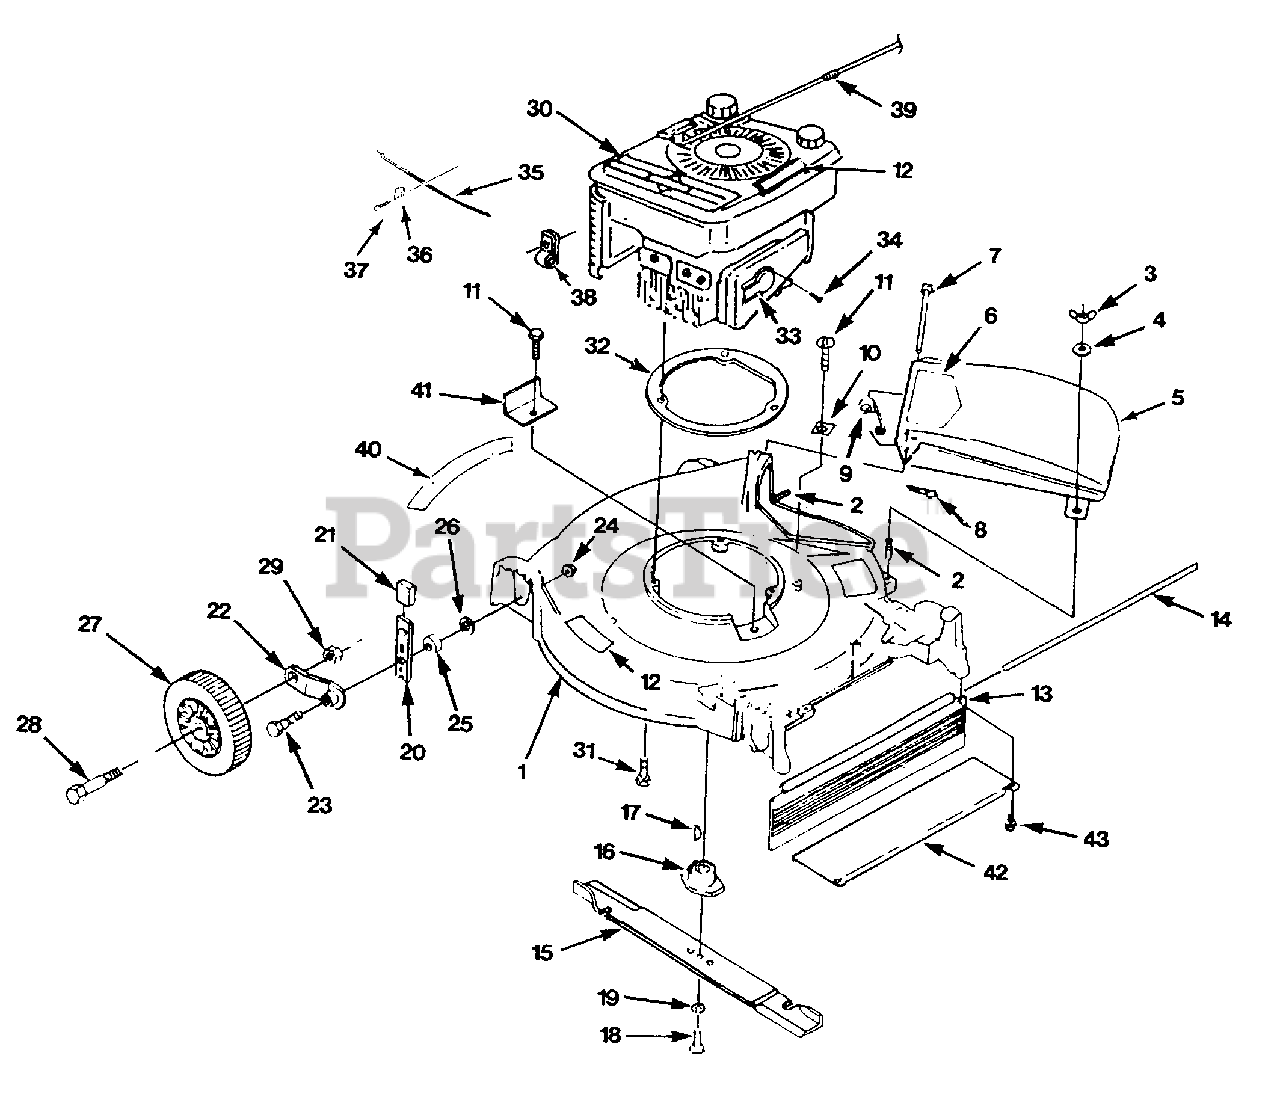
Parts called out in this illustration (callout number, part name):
1	Deck 20" push
2	Stud - 1/4-20 x 3/4
3	Nut - wing 1/4-20 nylock
4	Washer - flat 1/4
5	Cover - discharge opening
6	Decal - DANGER CPSC
7	Pin - hinge
8	Pin - cotter
9	Spring - cover
10	Bracket - rear bagger
11	Screw - hex tap 1/4-20 x 1/2
12	Decal - DANGER, blade
13	Flap - drag
14	Rod - drag flap
15	Blade - cutter 20"
16	Adapter - blade
17	Key - woodruff #61
18	Bolt - hex 3/8-24 x 1-1/4 Gde 8
19	Washer - split lock 3/8 hvy
20	Lever - height adjuster
21	Tip - adjuster lever
22	Arm - wheel mount
23	Bolt Hex 5/16-18 x 1 - 5/8 shldr
24	Nut - hex 5/16-18 flnge lock
25	Spacer - adjuster lever
26	Washer - flat 5/16
27	Wheel 8"
28	Bolt - wheel w/nut
29	Nut - hex jam 3/8-16 cntr lock
30	Engine
31	Bolt - hex 3/8-16 x 1 1/2
32	Ring - engine
33	Deflector - muffler
34	Screw-tap #8-32 x 3/8
35	Control - throttle w/cable
36	Clamp - cable
37	Screw - tap #10-16 x 5/8
38	Clip - cable
39	Stop - rope
40	Decal - logo
41	Cover - belt opening
42	Cover - rear
43	Screw - hex 1/4 - 20 x 3/4
